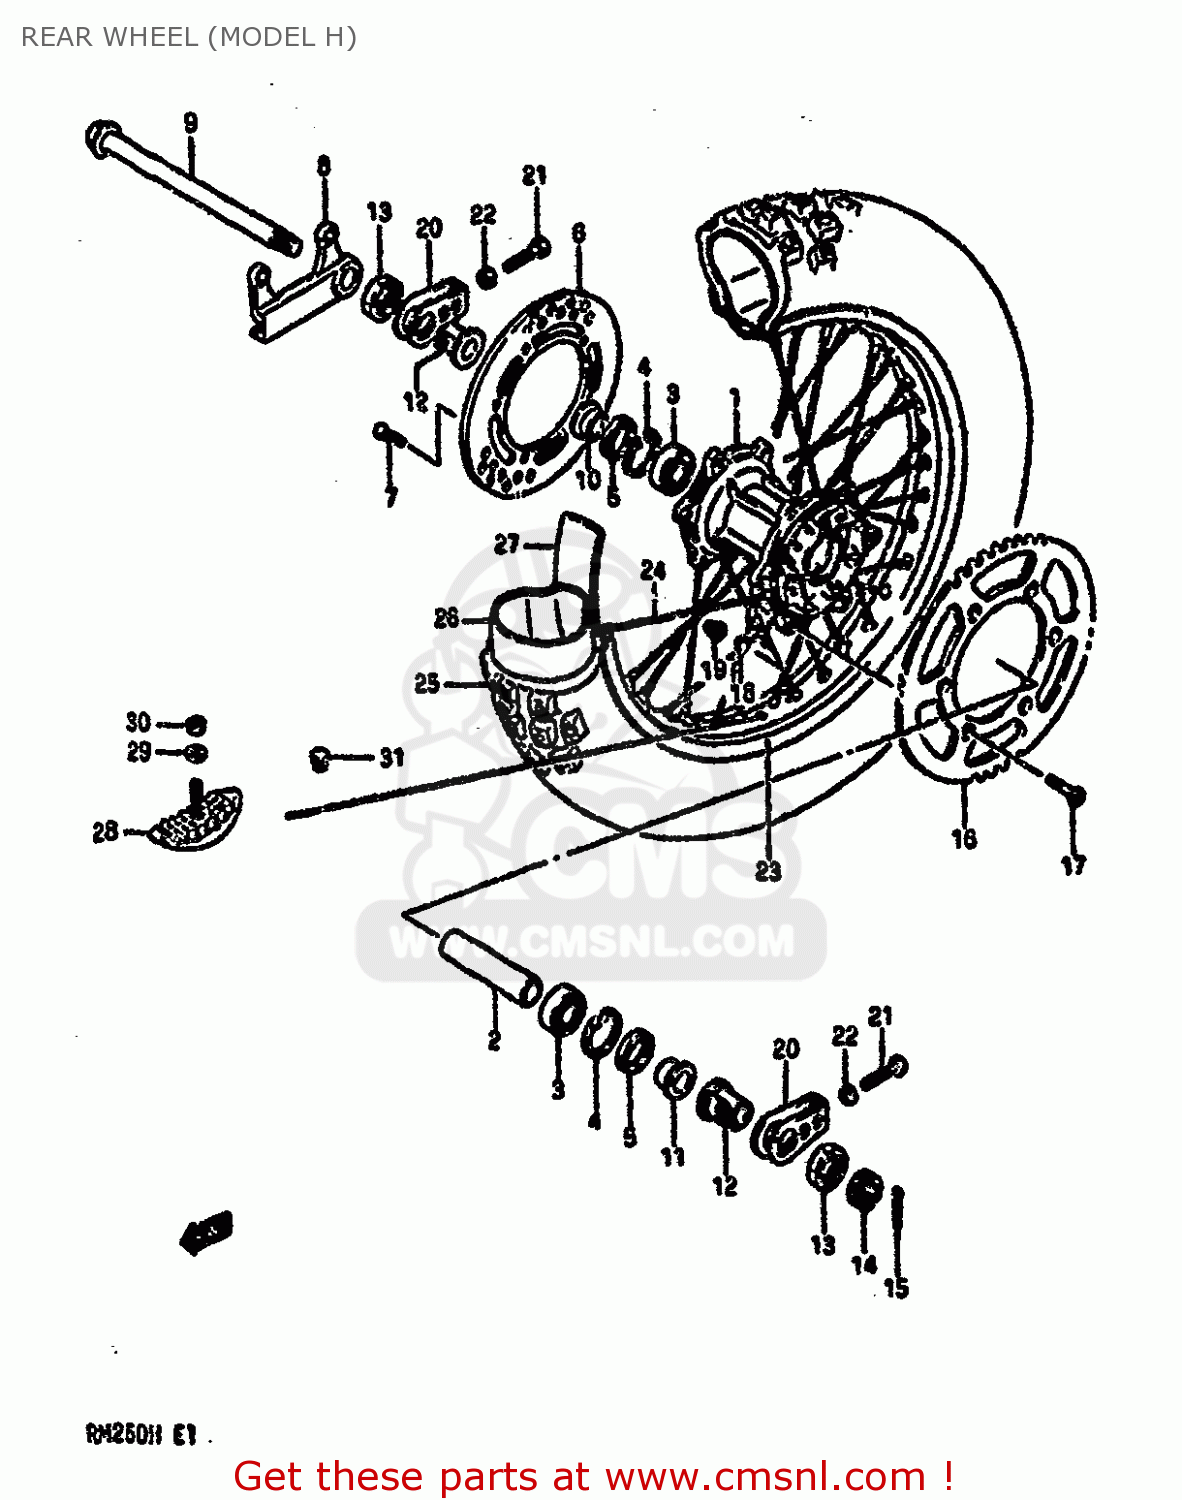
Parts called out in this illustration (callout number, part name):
1	HUB,REAR WHEEL
2	SPACER,BEARING
3	BEARING
4	CIRCLIP,14MM
5	OIL SEAL
6	DISC,REAR BRAKE
7	SCREW
8	BRACKET,REAR CALIPER
9	AXLE,REAR
10	SPACER,REAR AXLE
11	SPACER COMP,REAR AXLE
12	SPACER,CHAIN ADJUSTER
13	NUT
14	NUT 18MM
15	PIN,COTTER
16	SPROCKET,REAR
17	SCREW(8X33.5)
18	WASHER
19	NUT
20	ADJUSTER, CHAIN
21	BOLT(8X43)
22	NUT
23	RIM,REAR WHEEL
24	SPOKE SET,REAR WHEEL
25	TIRE
26	TUBE,INNER
27	PROTECTOR,WHEEL,INNER
28	STOPPER,BEAD
29	WASHER
30	NUT 8MM
31	CAP(OD:12)
